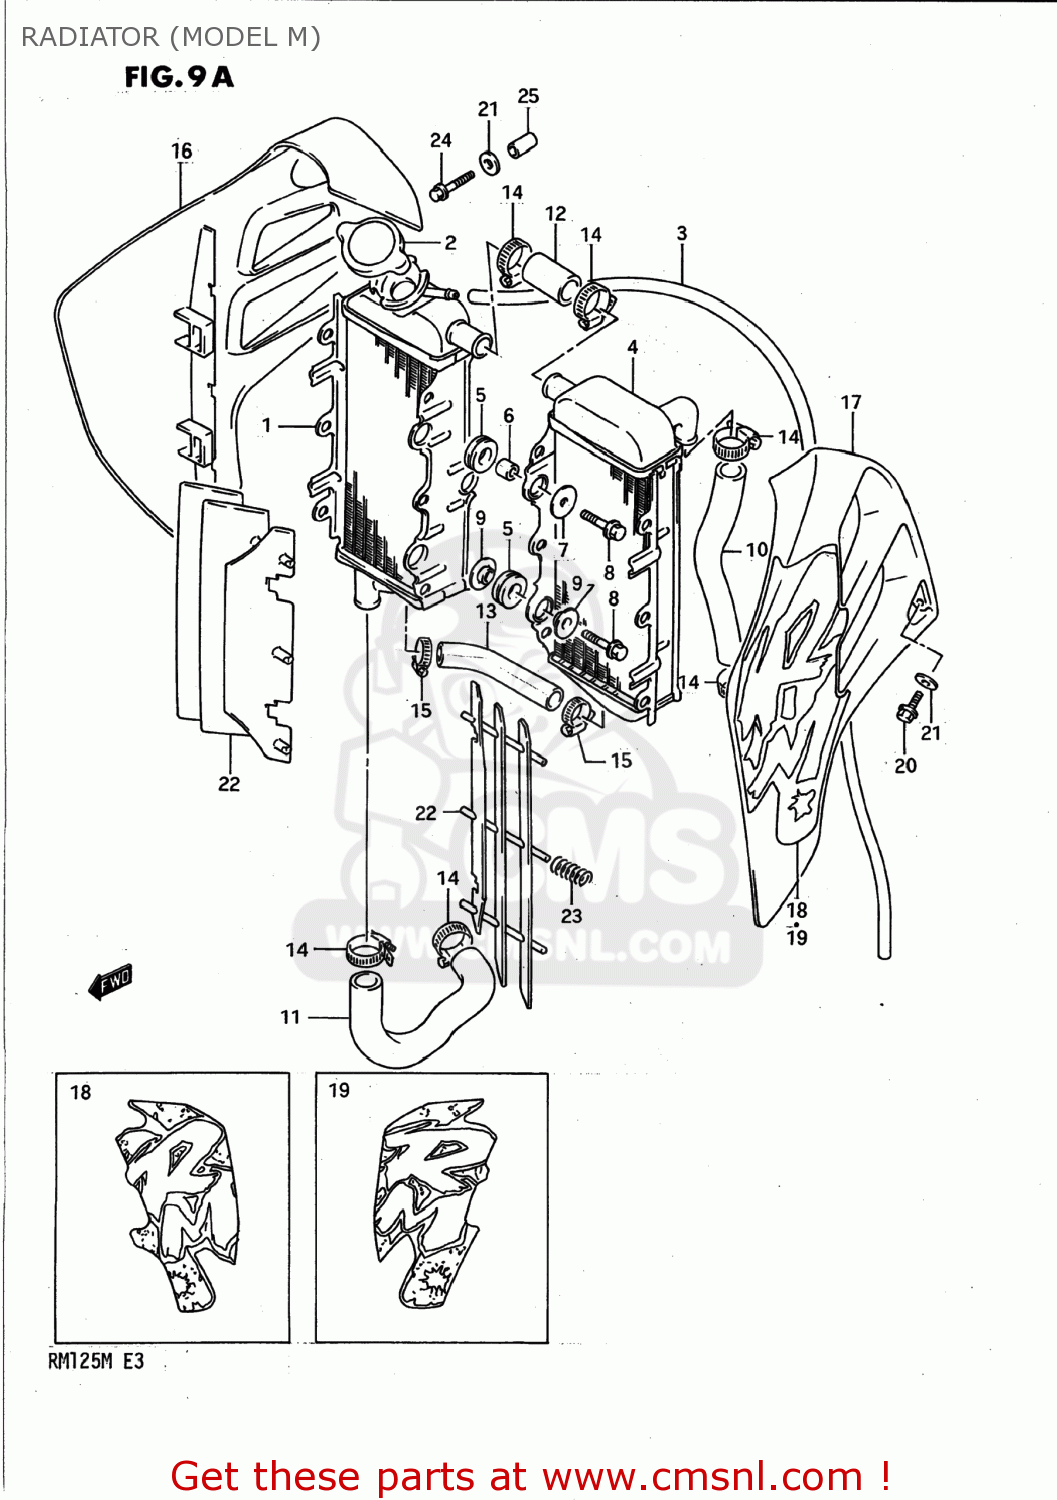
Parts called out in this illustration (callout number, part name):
1	RADIATOR COMP,WATER,RIGHT
2	CAP,RADIATOR 1.1
3	HOSE
4	RADIATOR COMP,WATER,LEFT
5	CUSHION,RADIATOR LWR
6	SPACER(6.5X10.5X12)
7	WASHER (6.5X24X1.2)
8	BOLT
9	WASHER,RDTR SPRT
10	HOSE,RADIATOR INLET
11	HOSE,RADIATOR
12	HOSE,RADIATOR JOINT NO.1
13	HOSE,WATER
14	CLAMP
15	CLAMP
16	COVER COMP,RADIATOR,RIGHT
17	COVER,RADIATOR,LEFT
18	EMBLEM,RADIATOR COVER
19	EMBLEM,RADIATOR COVER
20	BOLT
21	GASKET(6.5X20X1.5) (NAS)
22	LOUVER,RADIATOR
23	SPRING
24	BOLT
25	SPACER(6.4X10X22)
